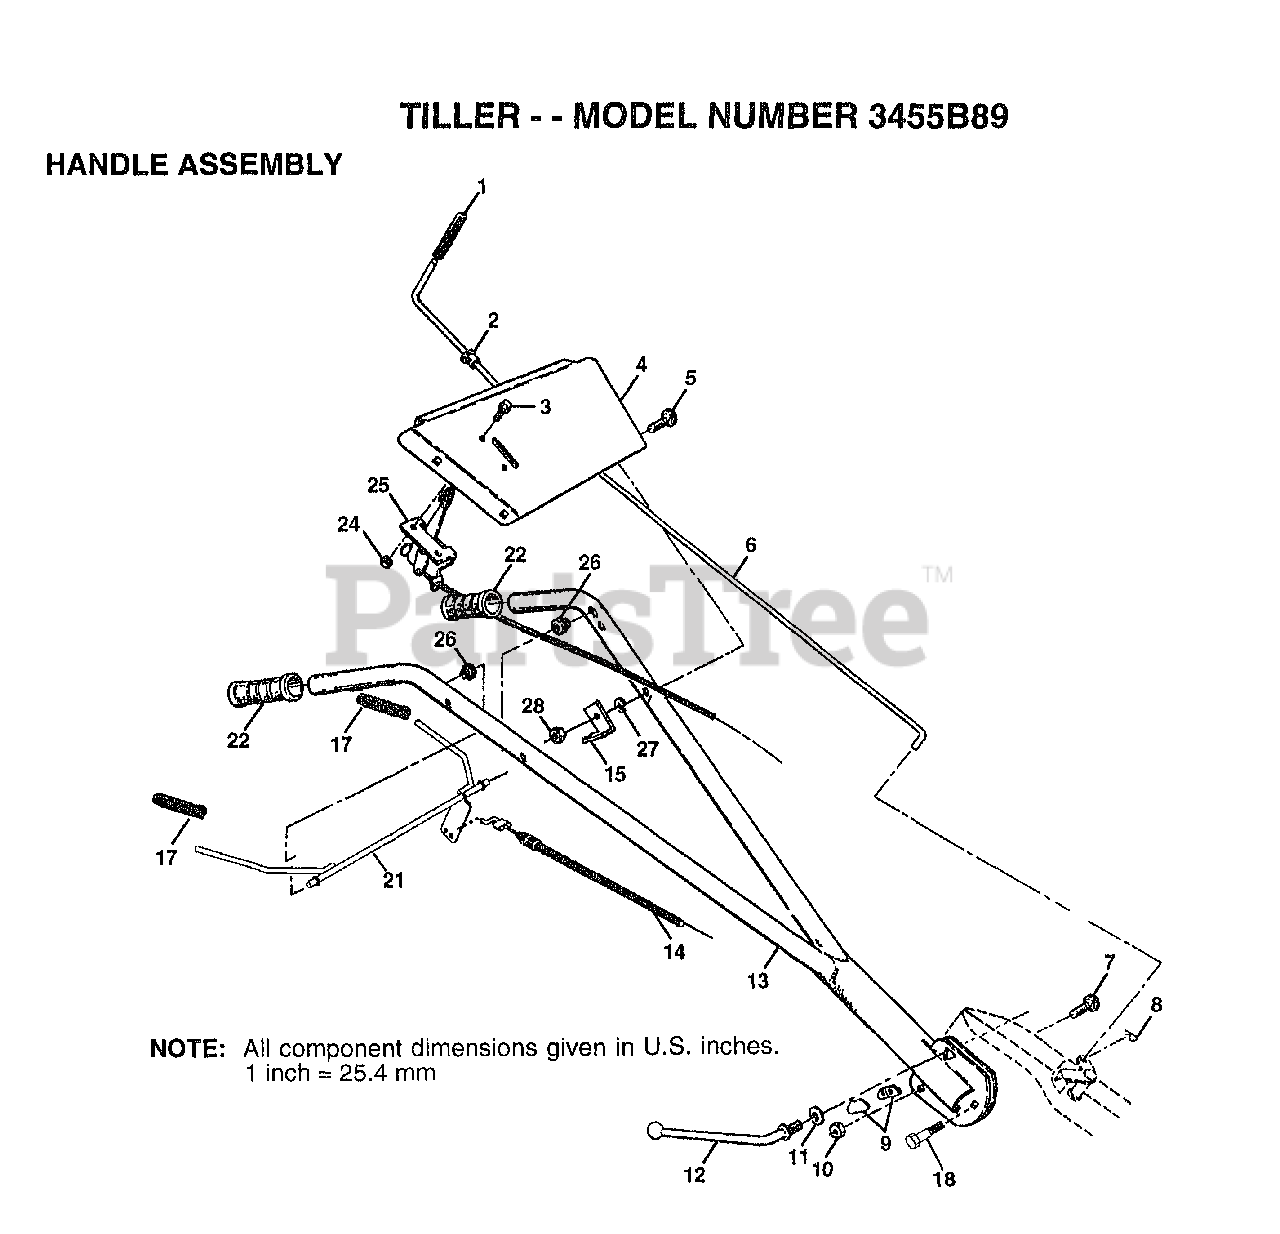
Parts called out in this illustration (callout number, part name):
1	GRIP TI
2	BUSHING
3	SCREW.PNHD.10-24
4	HANDLE BRACKET
5	BOLT CARRIAGE CRT
6	ROD SHIFT CRT
7	BOLT D
9	LOCK CRT
10	LOCKNUT
11	WASHER CRT
12	LEVER LOCK CRT
14	"CABLE, CLUTCH"
15	BRACKET.CLUTCH.CA
17	GRIP BAR CRT
18	BOLT PIVOT
22	"GRIP,HANDLE"
25	"CONT,THROTTLE"
26	GROMMET.HANDLE.V-
27	LOCKWASHER
28	NUT
